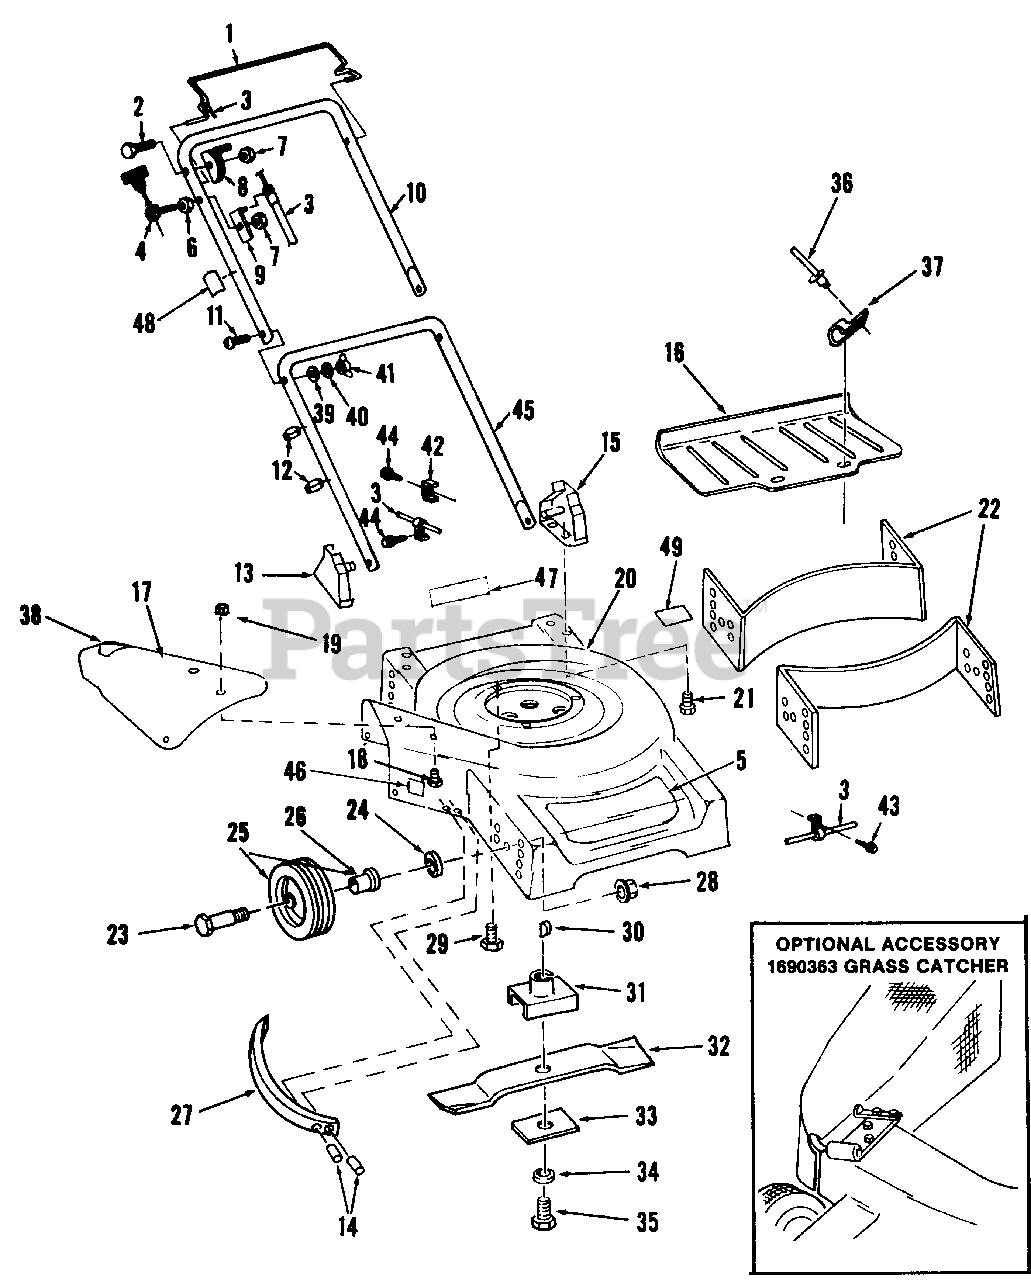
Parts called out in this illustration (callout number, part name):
1	Bail-Control
2	Bolt-Throttle 1/4-20 x 1-1/2
3	Control Cable
5	Decal-Deck, Simplicity
6	Nut-1/4-20 Hex
7	Nut-Hex 1/4-20 Locking
8	Control-Throttle
9	Bracket-Cable Mounting
10	Handle-Upper
11	Bolt-Handle
12	Clamp-Cable
13	Bracket Assembly-Yoke, R.H.
14	Rivet-1/4" Pop
15	Bracket Assembly-Yoke, L.H.
16	Trailguard
17	Chute Extension
18	Bolt-Carriage
21	Bolt-1/4-20 x 1/2
23	Bolt-Shoulder
24	Washer-3/8 Flat
25	Wheel Assembly w/Bearing 7"
26	Bearing-Wheel
27	Guard-Blade
28	Nut-Baffle
29	Screw-Engine
30	Key-Engine Shaft
31	Blade Adapter Assembly
33	Spacer-Blade Adapter
34	Washer-Blade
36	Pop Rivet
37	Clip-Trailguard
38	Decal-Danger & Caution
39	Washer-Curved
40	Washer-Lock
42	Clamp-Casing
43	Screw-Hex Head
44	Screw-Casing
45	Lower Handle
46	Decal-19"
47	Decal-Simplicity 6"
48	Decal-Engine Control
49	Decal-Starting Instructions
49	Grass Catcher
49	Replacement Bag
